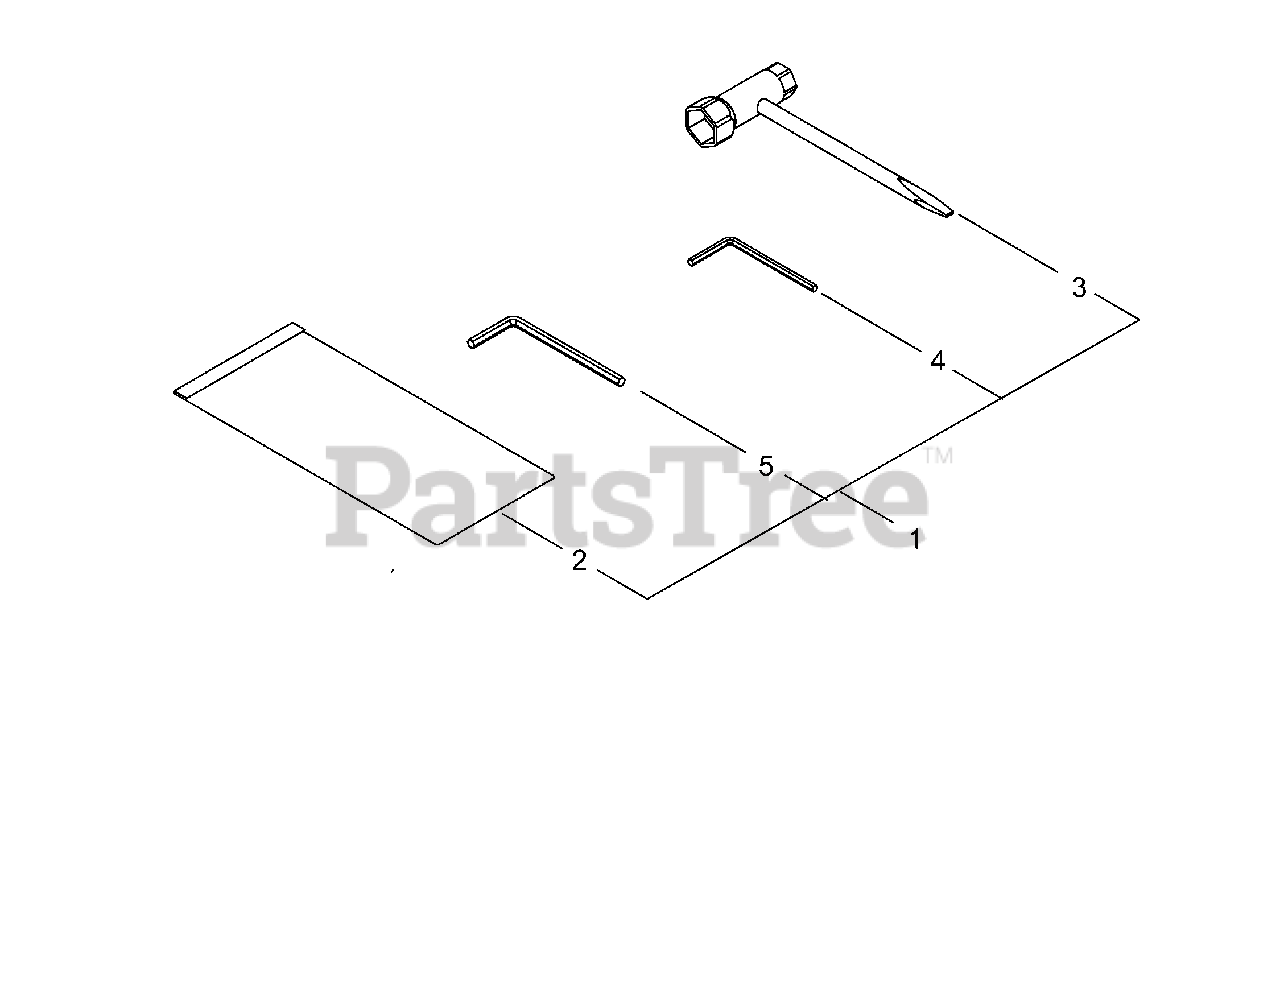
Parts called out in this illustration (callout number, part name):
1	TOOL KIT, SERVICE
2	BAG, TOOL
3	T-WRENCH 17×19mm
4	WRENCH, ALLEN 4MM
5	WRENCH, ALLEN 5MM
